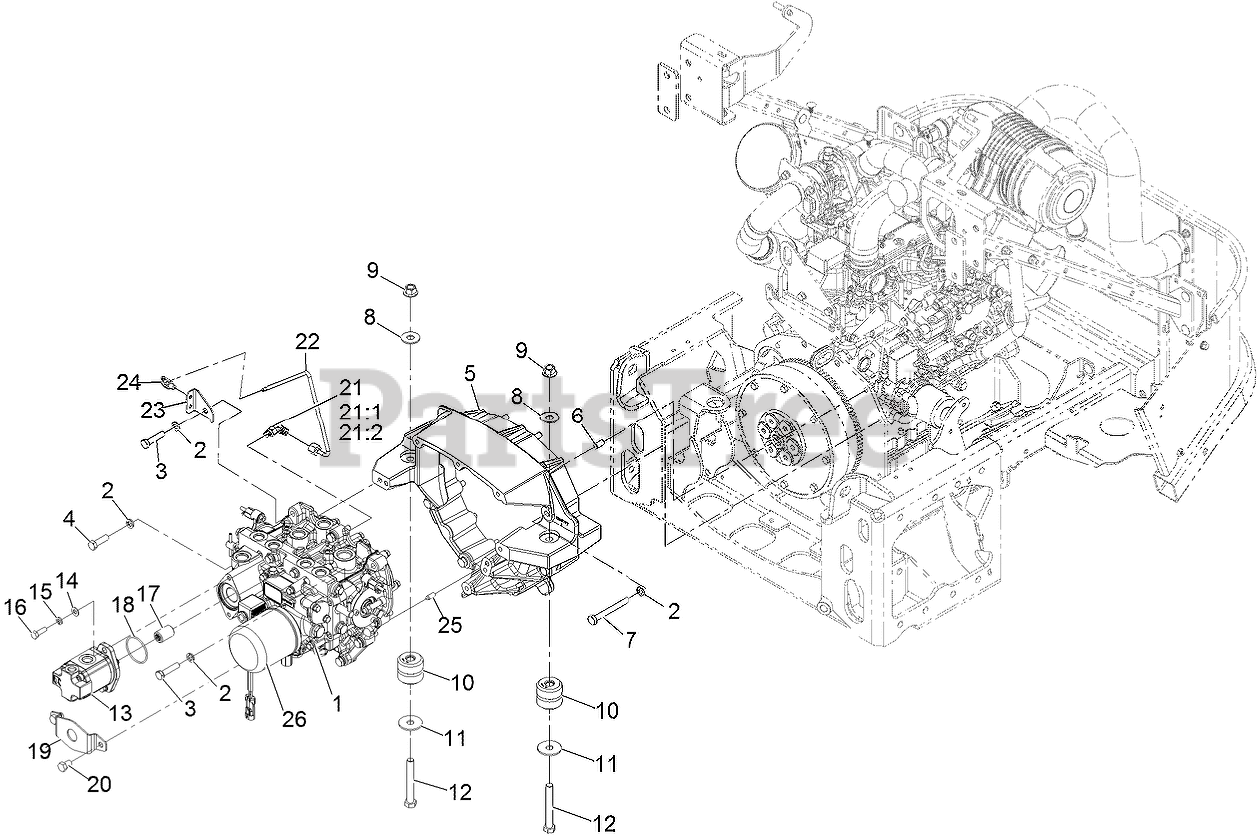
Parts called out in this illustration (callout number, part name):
1	TRANSMISSON ASM
2	WASHER-LOCK
3	SCREW-HH
4	SCREW-HH
5	Housing-Flywheel
6	PIN-DOWEL
7	SCREW-HH
8	WASHER-FLAT
9	Nut-Lock 1/2-13
10	MOUNT-ISOLATOR
11	WASHER-THRUST
12	SCREW-HH
13	HYD GEAR PUMP ASM
14	WASHER-PLAIN
15	WASHER-LOCK
16	SCREW-HH
17	COUPLER-SPLINE
19	SHIELD-SEAL
20	SCREW-HH
21	FITTING-ELBOW, 90 DEG
21:1	O-RING
21:2	O-RING
22	TUBE ASM
23	SUPPORT-TUBE
24	CLIP-TIE
25	PIN-DOWEL
26	FILTER-OIL, HYD
